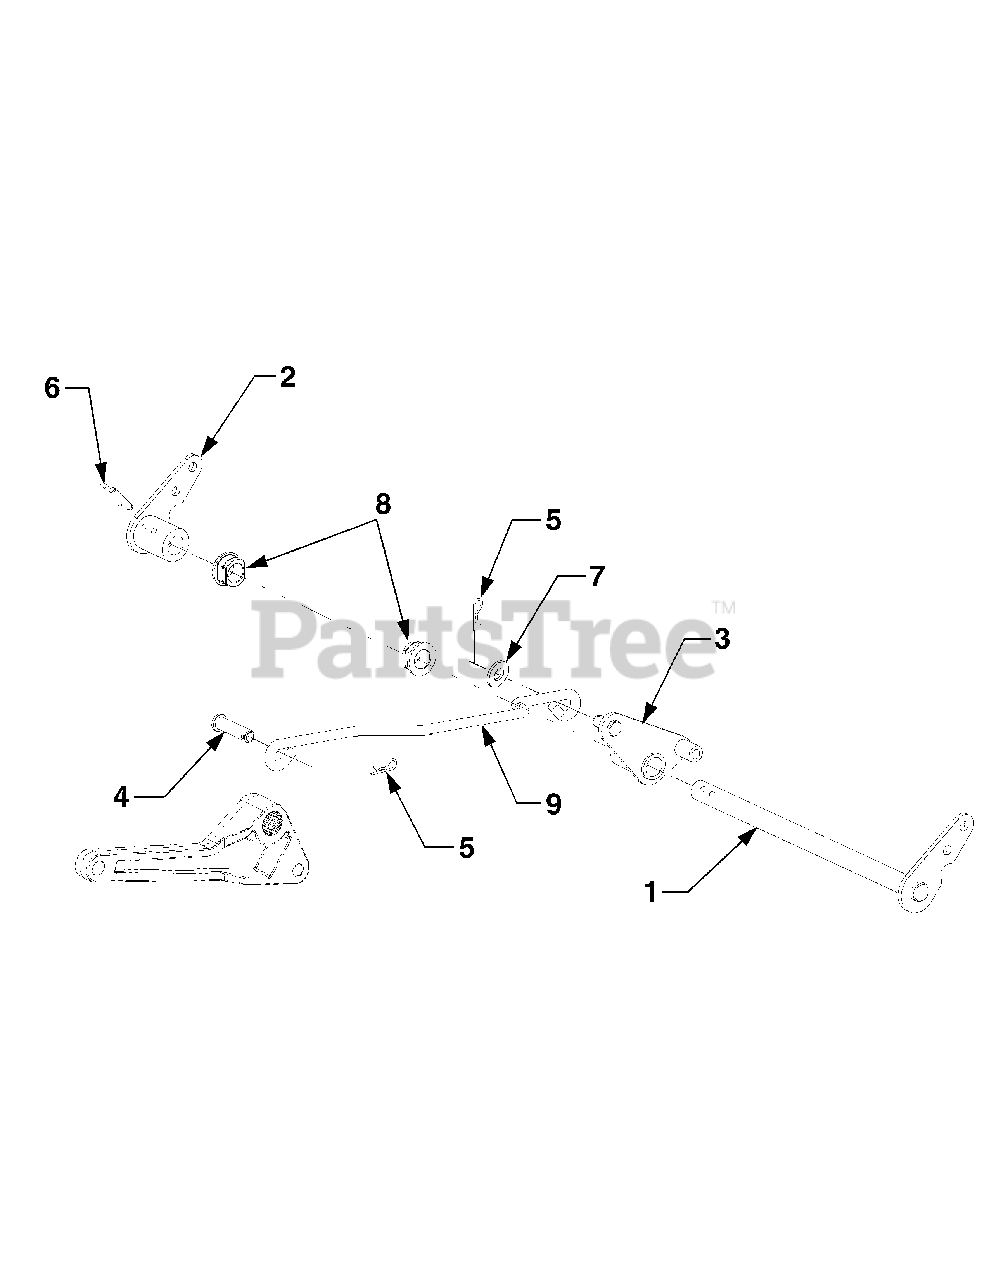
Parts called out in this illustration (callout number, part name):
3	Plate, Lift Crank
4	Pin, Clevis, .625 x 2.18
5	Pin, Internal Cotter
6	Pin, Spirol, 5/16 x 1.75
7	Washer, Flat, .635 x 1.24 x .181
8	Bearing, Flange w/Flats
9	Rod, Crank Lift
